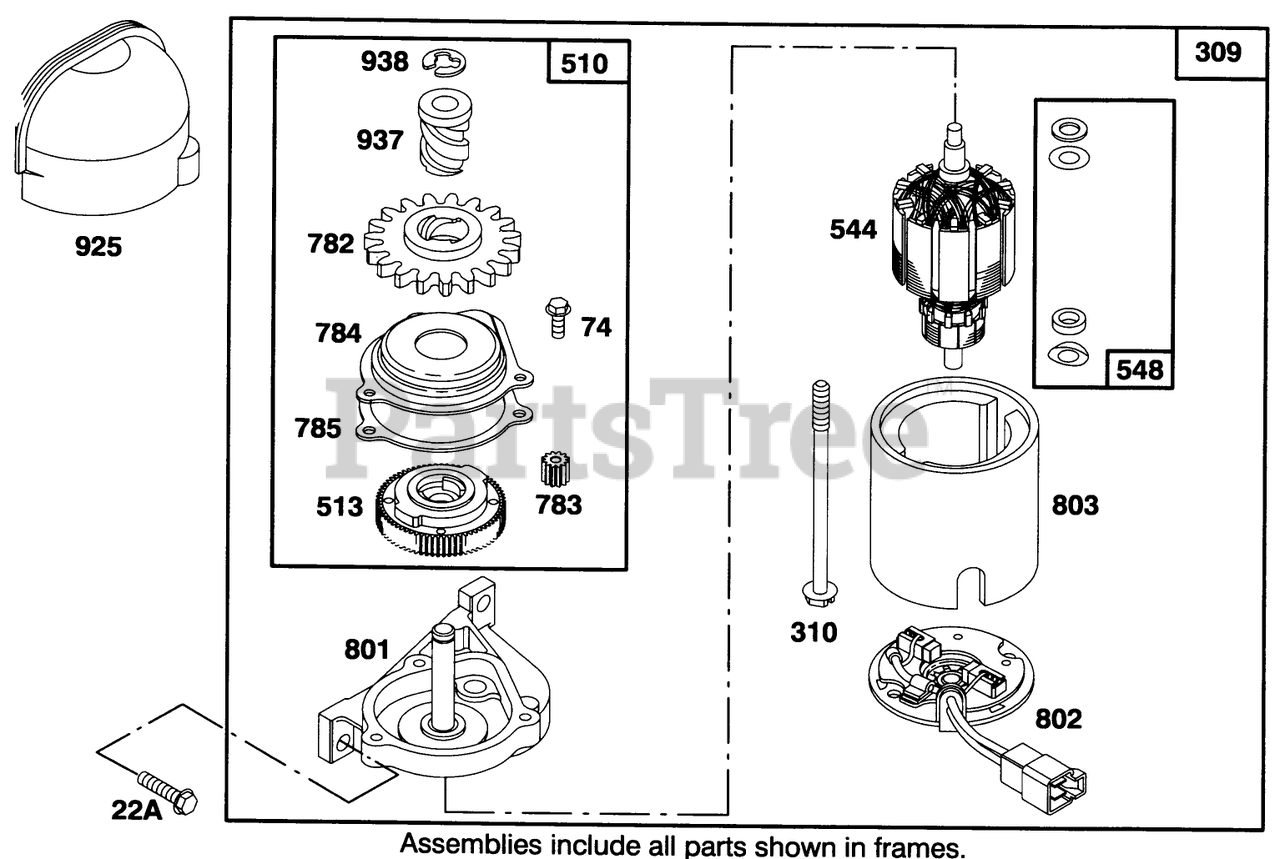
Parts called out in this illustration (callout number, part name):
22A	SCREW - CARBUERTOR MTG
510	DRIVE SET
513	CLUTCH - STARTER
548	WASHER ASSEMBLY
782	GEAR - STARTER
925	COVER - STARTER
938	RETAINER - LOCK
